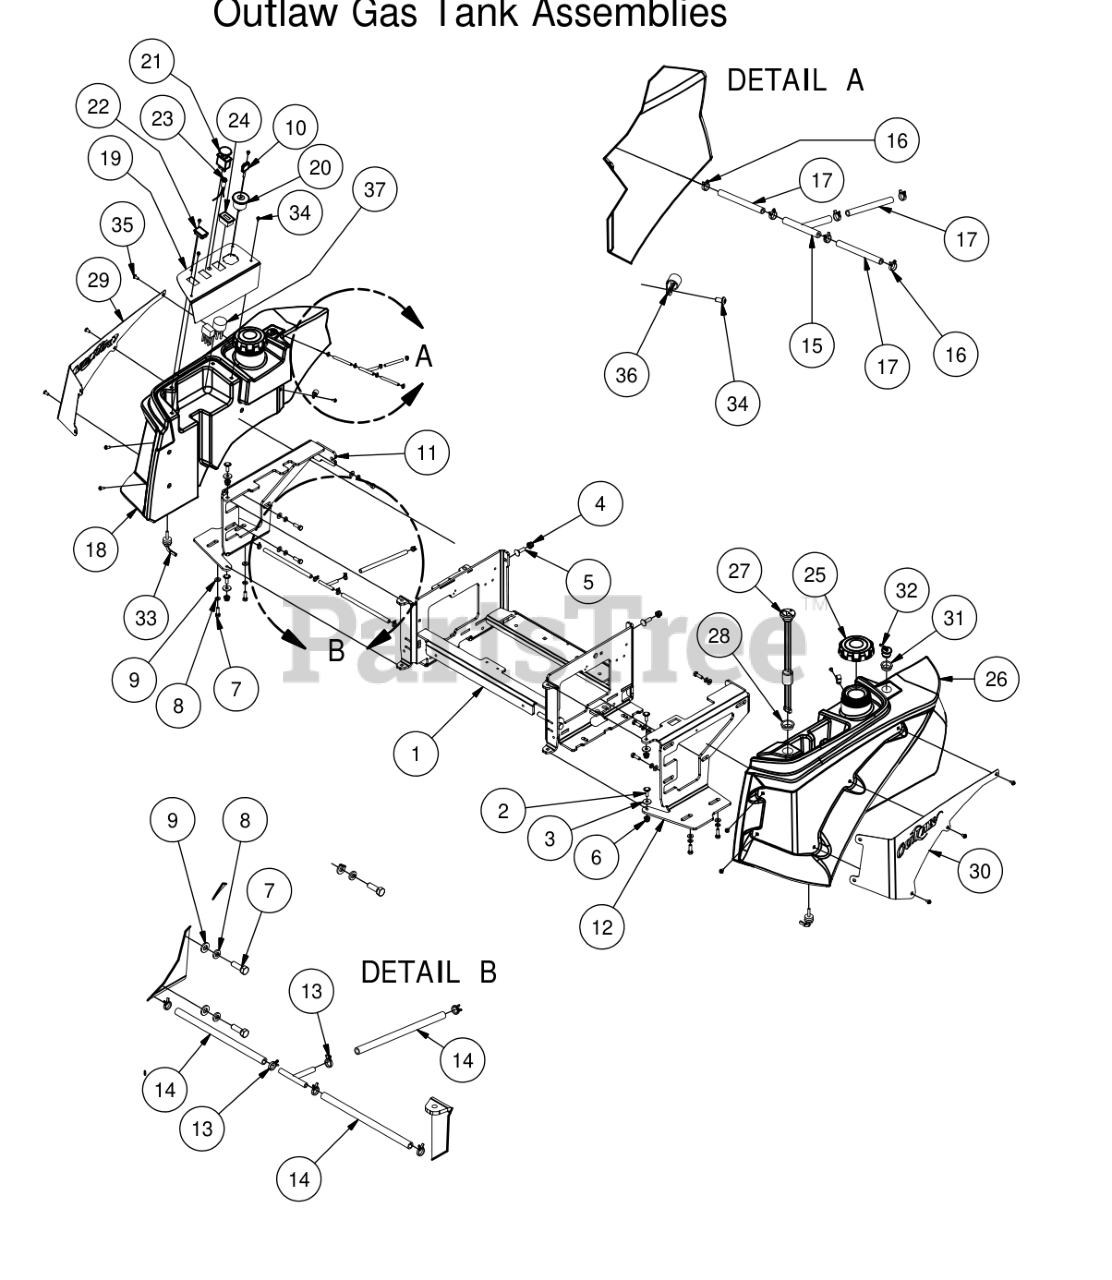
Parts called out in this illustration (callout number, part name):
1	2016 Outlaw Seat Bracket
2	5/16-18 x 1 Carriage Bolts Zinc
3	.360 ID Plastic Washer
4	3/8" Nylock Flange Nut
5	3/8" x 1 1/4" Carriage Bolt
6	5/16-18 Nylon Insert Flange Nut Zinc Orange Nylon
7	5/16" x 1" Bolt
8	5/16" Lock Washer
9	5/16" Flat Washer
10	Ignition Key
11	Outlaw 2015 Tank Support (Right)
12	Outlaw 2016 Tank Support (Left)
13	1/4 Fuel Hose Clamp
14	1/4" Fuel Line Hose
15	fuel line T
16	3/16 Vinyl Clamp
17	1/4" Vinyl Tubing
18	Outlaw 2015 Fuel Tank (Right)
19	Analog Control Panel Outlaw
20	Ignition Switch
21	PTO Switch
22	Light Plug
24	Tachometer
25	Fuel Cap (Kelch)
26	Outlaw 2015 Fuel Tank (Left)
27	Fuel Gauge w/Grommet
28	Grommet for Fuel Gauge
29	Outlaw Tank Panel (Right)
30	Outlaw Tank Panel (Left)
31	ROV Grommet
32	Rollover Valve - Black
33	Fuel Tank Hose Nipple w/Filter
34	10-32 x 3/8" Button Socket Head Bolt
35	1/4" x 1/2" BS C/S 18-8 SS
36	3/8 Cable Clamp-Black Nylon
37	Wiring Harness
